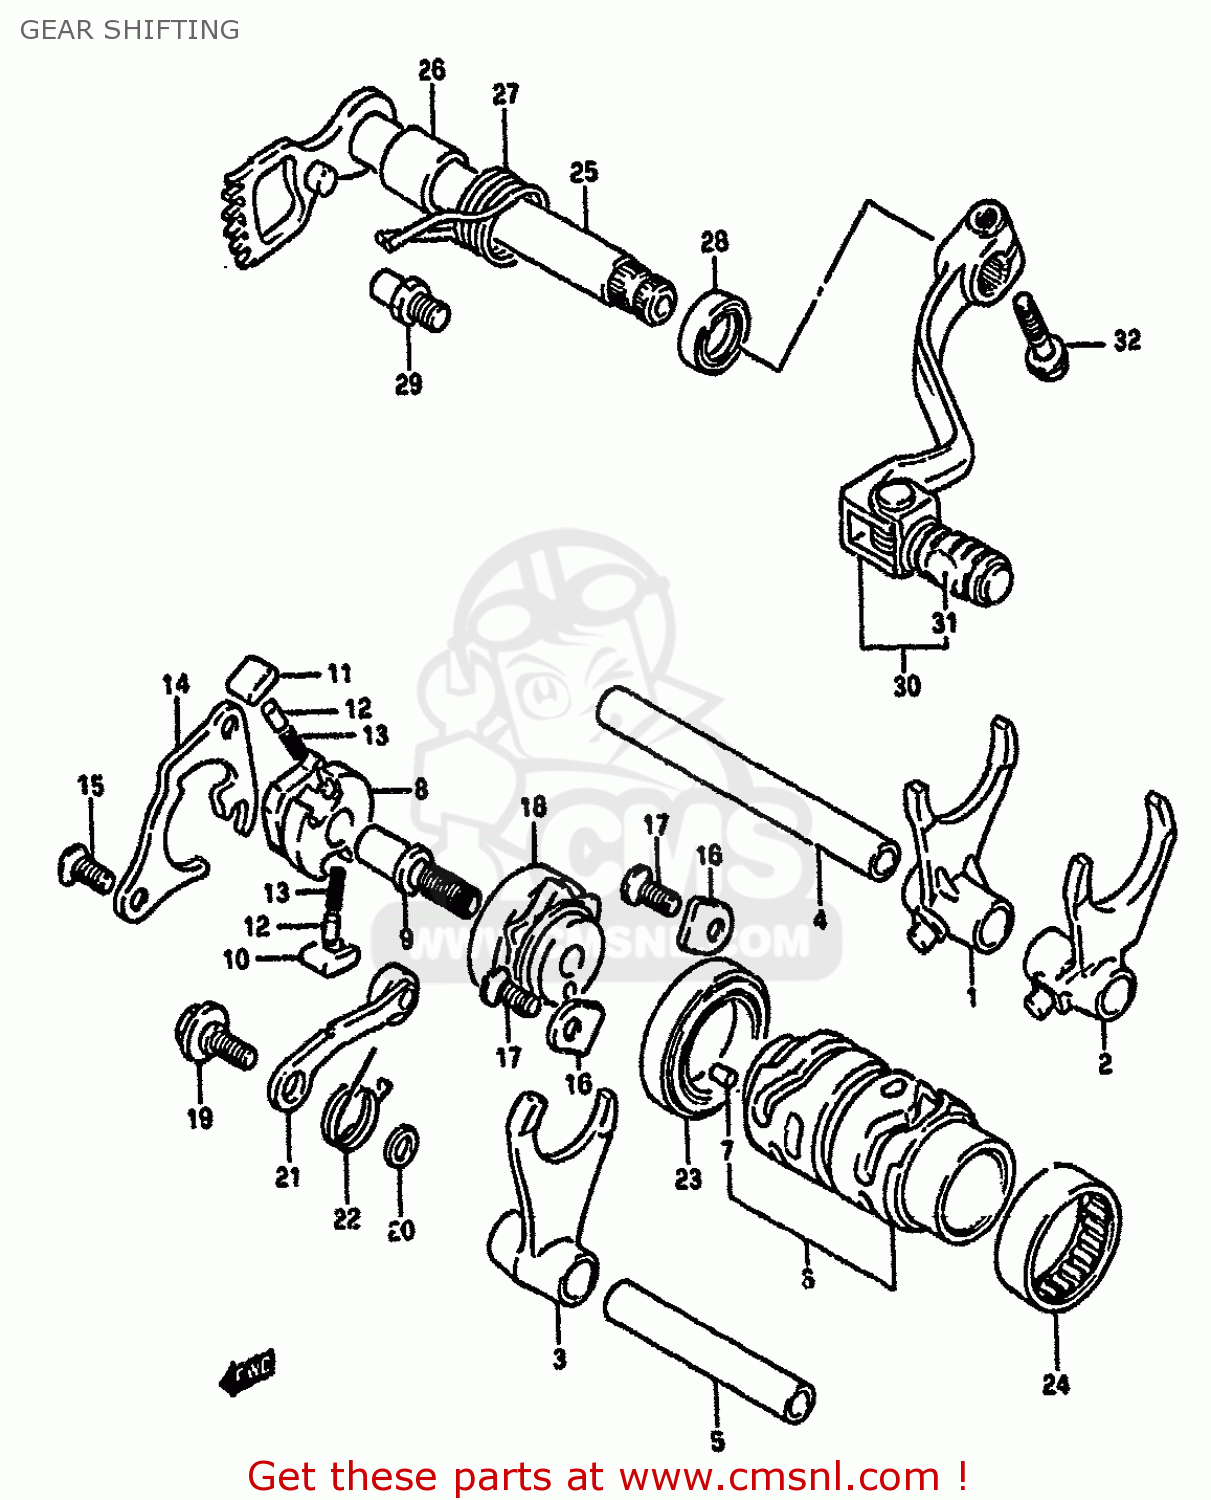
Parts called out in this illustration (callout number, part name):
1	FORK,GEAR SHIFT NO.1
2	FORK,GEAR SHIFT NO.2
3	FORK,GEAR SHIFT NO.3
4	SHAFT,GEAR SHIFT FORK
5	SHAFT,GEAR SHIFT FORK
6	CAM,GEAR SHIFT
7	PIN(4X11.8)
8	GEAR,GEARSHIFT CAM DRIVE
9	PIN,SHIFT CAM DRIVEN GEAR
10	PAWL,GEAR SHIFT NO.1
11	PAWL,GEAR SHIFT NO.2
12	PIN(5X8)
13	SPRING
14	LIFTER,GEAR SHIFT POLE
15	SCREW
16	RETAINER,COUNTER BEARING,R
17	SCREW
18	PLATE,GEAR SHIFT CAM STOPPER
19	BOLT(6X14.3)
20	WASHER
21	STOPPER,SHIFT CAM
22	SPRING
23	BEARING
24	BEARING(30X37X12)
25	SHAFT,GEAR SHIFT
26	SPACER(14X20X17.5)
27	SPRING
28	SEAL,OIL(14X22X7.3)
29	STOPPER,GEAR SHIFT CAM
30	LEVER ASSEMBLY,GEAR SHIFTING
31	RUBBER,GEAR SHIFT PEDAL
32	BOLT
